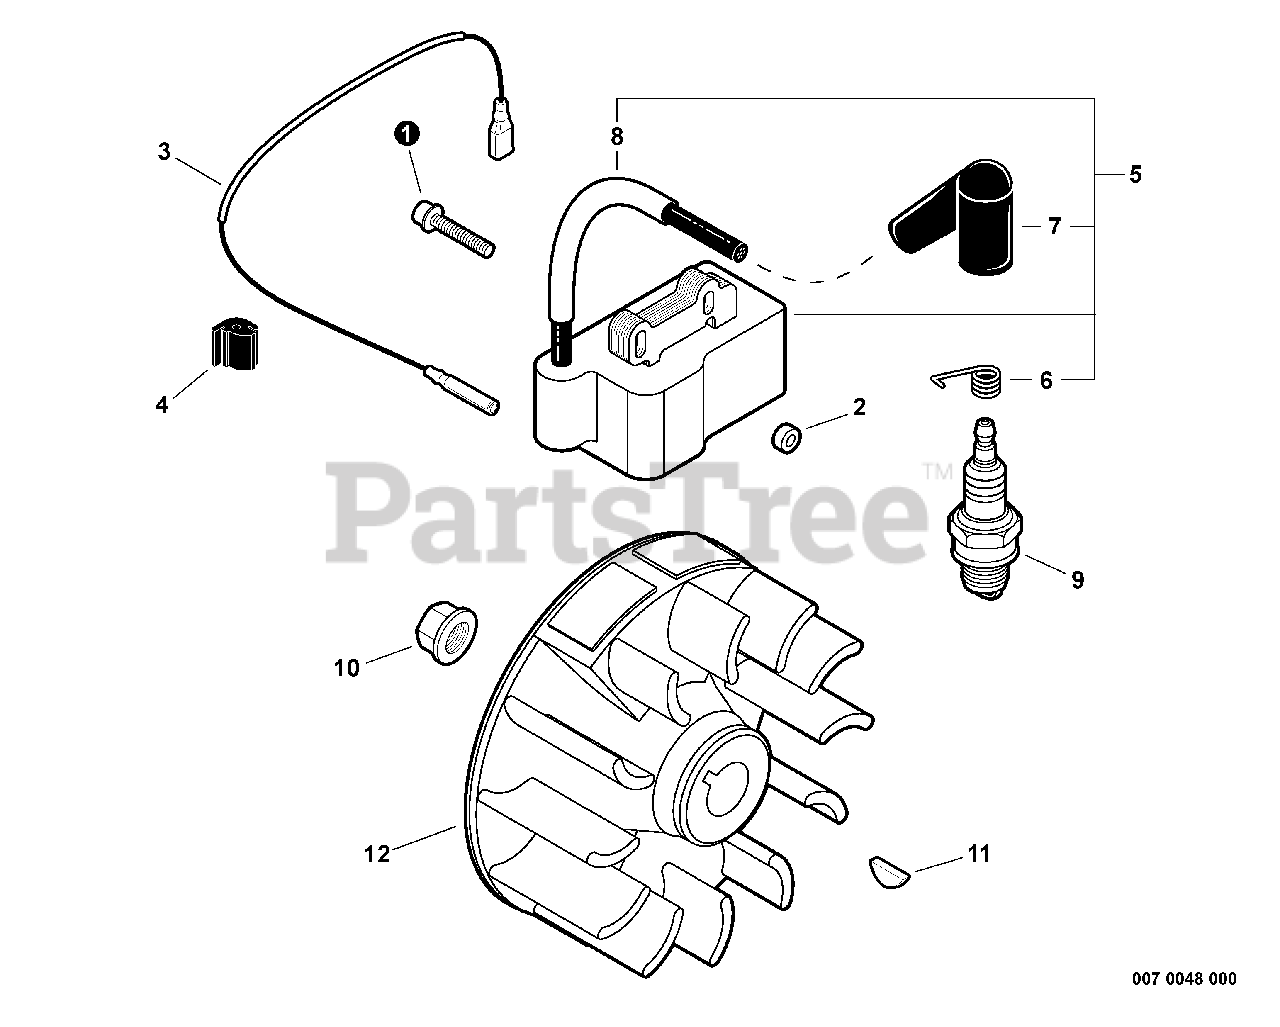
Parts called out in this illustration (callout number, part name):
1	SCREW - 4X26
2	INSULATOR
3	LEAD - IGNITION
4	GROMMET
5	IGNITION COIL ASSY
6	TERMINAL, SPARK PLUG CAP
7	CAP, SPARK PLUG
8	TUBE, INSULATOR
9	SPARK PLUG -- CMR-5H
10	NUT - 8
11	KEY - 3X10
12	FLYWHEEL
